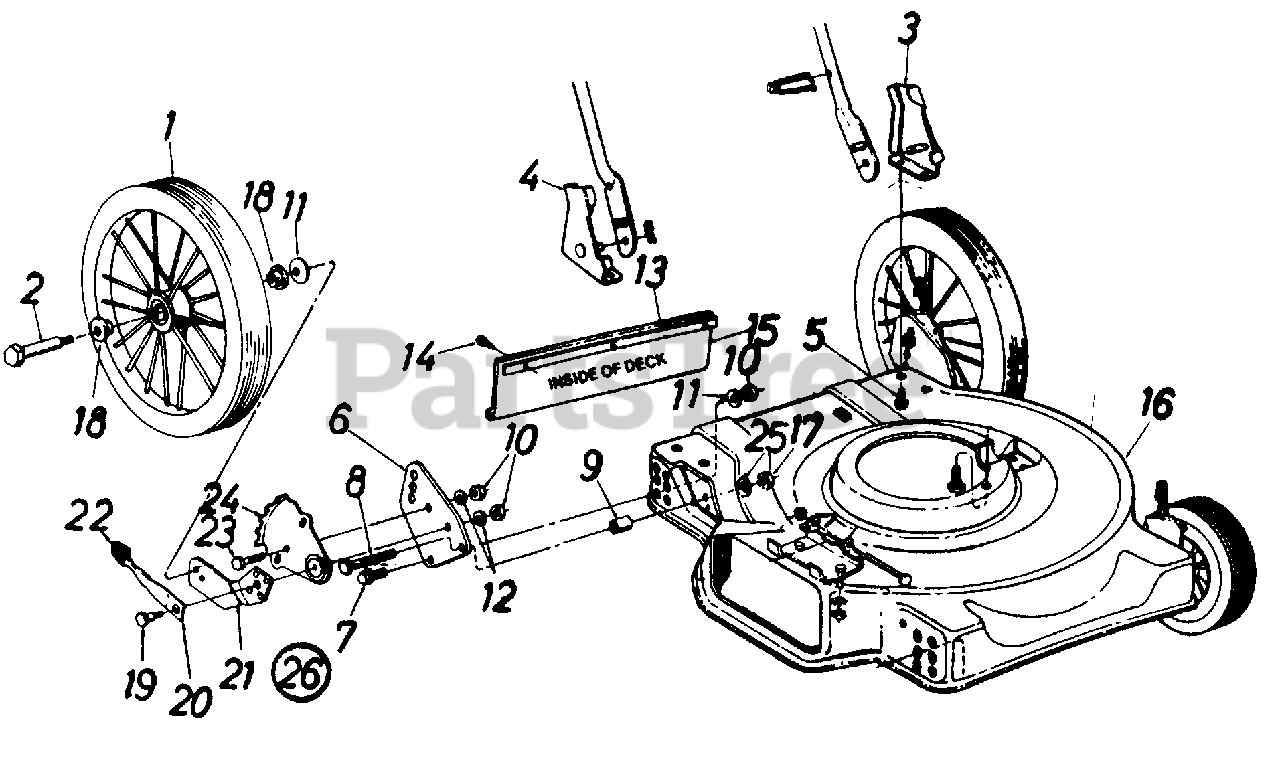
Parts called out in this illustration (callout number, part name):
1	Rear Wheel Ass'y. Comp.
2	Rear Axle Bolt
3	Handle Mount Brkt.-L.H.
4	Handle Mount Brkt.-R.H.
5	Hex B-Tap Scr. 5/16-18 x .5"
6	Mounting Plate
7	Hex Sems Bolt 3/8-16 x .62"
8	Hex Bolt 5/16-18 x 1.5" Lg.
9	Spacer
10	Hex Nut 3/8-16 Thd.
11	Bell-Wash. .40" I.D. x .88"
12	L-Wash. 3/8" I.D.
13	Retaining Strip
14	Hex AB-Tap Scr. 1/4" x .62"
15	Rear Flap Ass'y.
16	22" Deck Ass'y.
17	Hex Nut 5/16-18 Thd.
18	Flange Bearing
19	Shoulder Bolt
20	Spring Lever
21	Pivot Bar-R.H.
22	Spring Lever Knob
23	Hex Bolt 3/8-16 x .75" Lg.
24	Index Plate
25	Bell-Wash. .345" I.D.
26	Rear Height Adj. Ass'y. Comp.-R.H.
